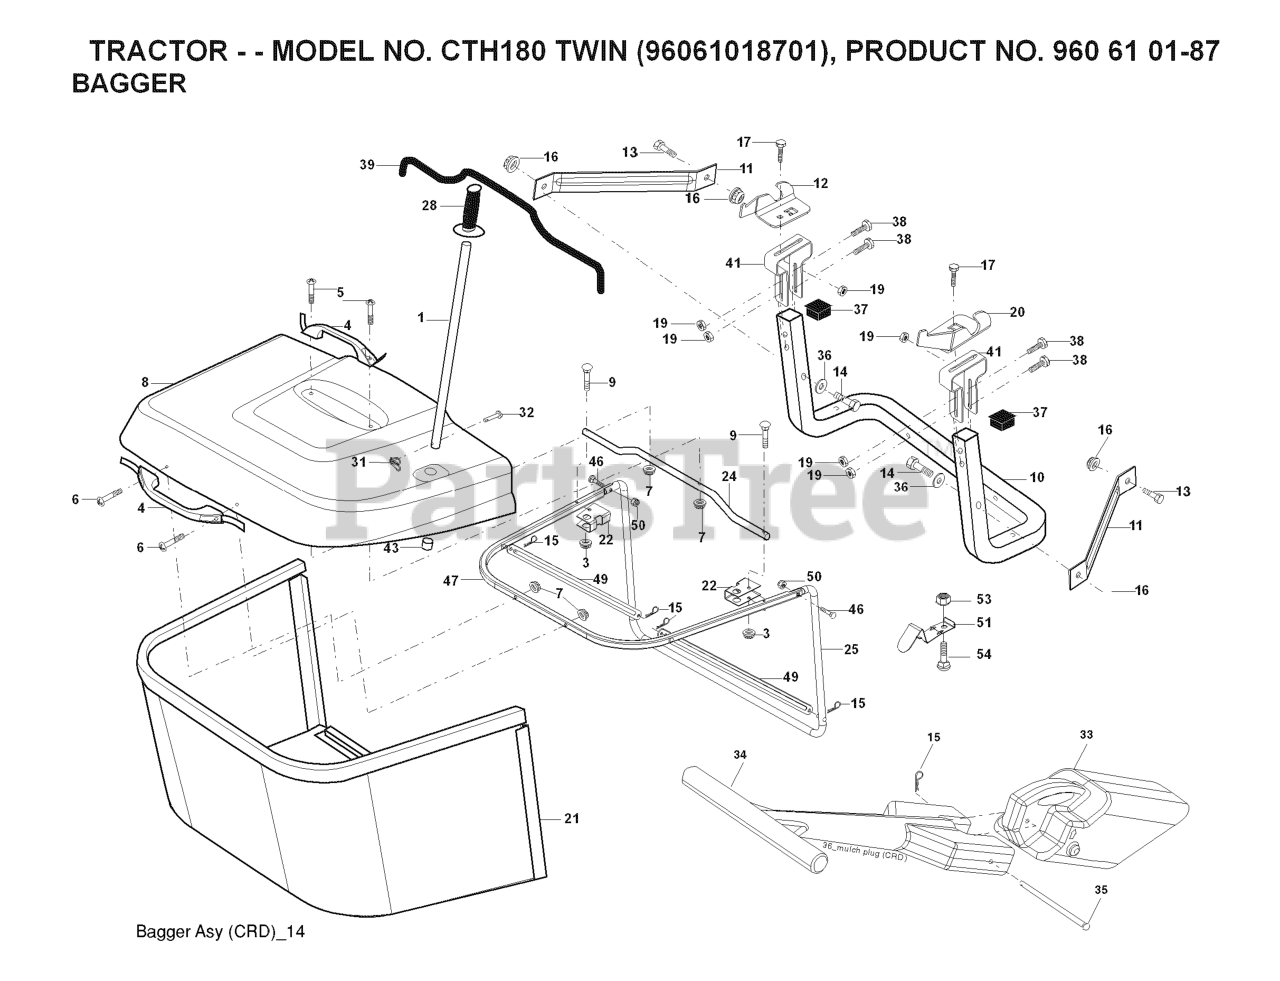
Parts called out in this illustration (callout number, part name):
1	TUBE HANDLE
3	NUT T
4	HANDLE.BAGGER.W/LVRS.BLK.CRD
5	SCREW.PAN.HEAD
6	REPL BY 532 75 00-29
8	COVER.PNT.BGR.CRD.WSLOTS.MS668
9	Bolt Carriage 1/4-20 x 2.25d x Gr.5
10	TUBE
11	BRACKET.SUPPORT.UPPER.BAG.CRD
12	BRKT PIVOT
14	BOLT-HEX EAK
15	RETAINER-SPRNG RB
16	NUT LOCK FLG 3/8-16 UNC
17	RP BOLT 5/16-18 X3/4 ZN/YEL GR
19	NUT LOCK HEX FLANGE 5/16-18
20	BRKT.PIVOT.RH.CRD
21	BAGGER.ASM.CRD.2007
22	BRKT.SIDE.BAG.CRD
24	TUBE.PIVOT.BAG.CRD.BLACK
25	PIPE
28	GRIP.HANDLE.BLACK
31	RETAINER CLIP
32	RIVET,DRILLED
33	MULCH PLUG, CTH150
34	HANDLE.MULCHER.92.CRD (2 2)
36	WASHER
37	Plug Support Bagger CRD
38	BOLT.5/16-18X2.5
39	SEAL.TRIM.37'
41	BRKT.VERT.ADJ.BAGGER.CRD
43	PLUG, TUBING END
46	BOLT.CARRIAGE.5/16-18
47	PIPE
49	ROD
50	NUT.71038.31-18.HEX.NYLOCK
51	LATCH
53	NUT
54	BOLT
